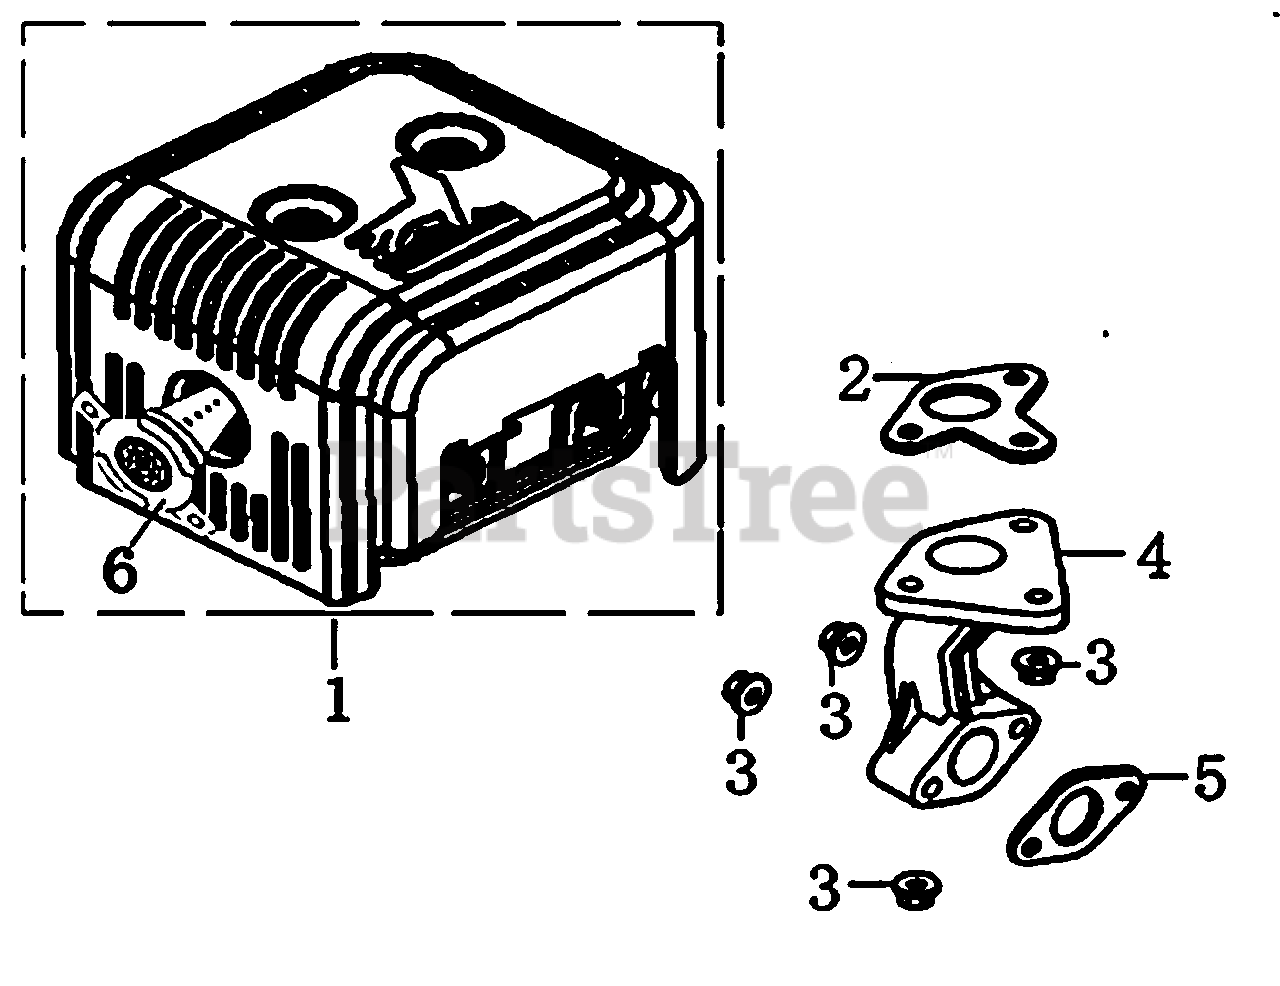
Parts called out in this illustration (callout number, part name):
1	MUFFLER ASSY.
2	GASKET, EXHAUST MANIFOLD
3	NUT, HEX M8
4	EXHAUST MANIFOLD
5	GASKET, MUFFLER
6	ARRESTER, SPARK
